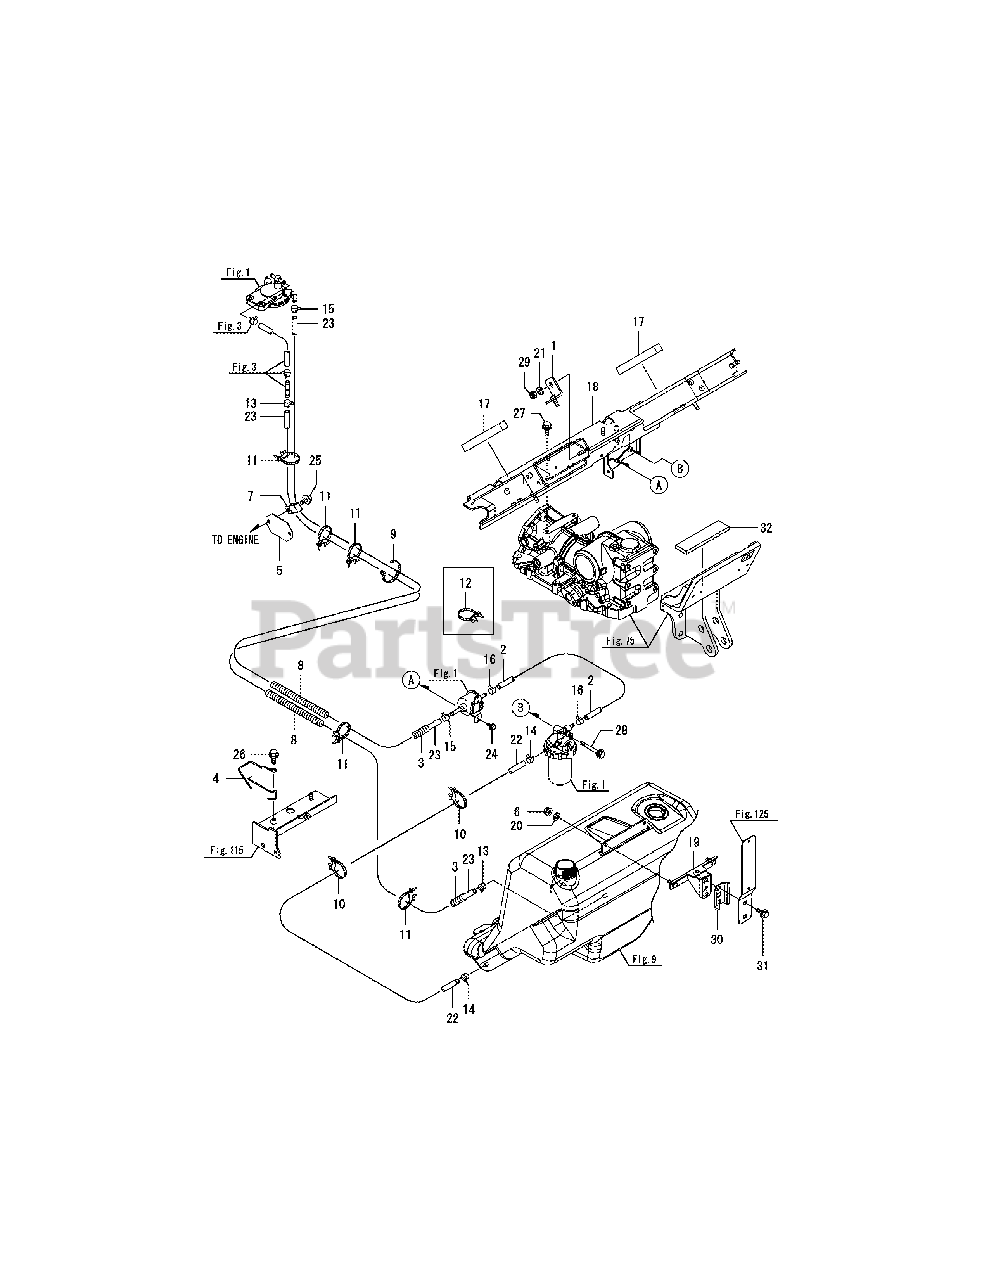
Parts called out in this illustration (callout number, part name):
1	ANGLE ASSY, TANK
3	TUBE, CORRUGATE 13
5	COVER, HOUSING
6	NUT W/WASHER 8
8	TUBE, CORRUGATE 13
18	BRACKET ASSY, TANK
19	BRACKET, SMV ASSY
23	HOSE, 7.3X1700
24	BOLT M 6X 12 PLATED
25	BOLT M 8X 16 PLATED
26	BOLT M 8X 16 PLATED
27	BOLT M 8X 20 PLATED
28	BOLT M 8X 70 PLATED
31	BOLT M 8X 20 PLATED
